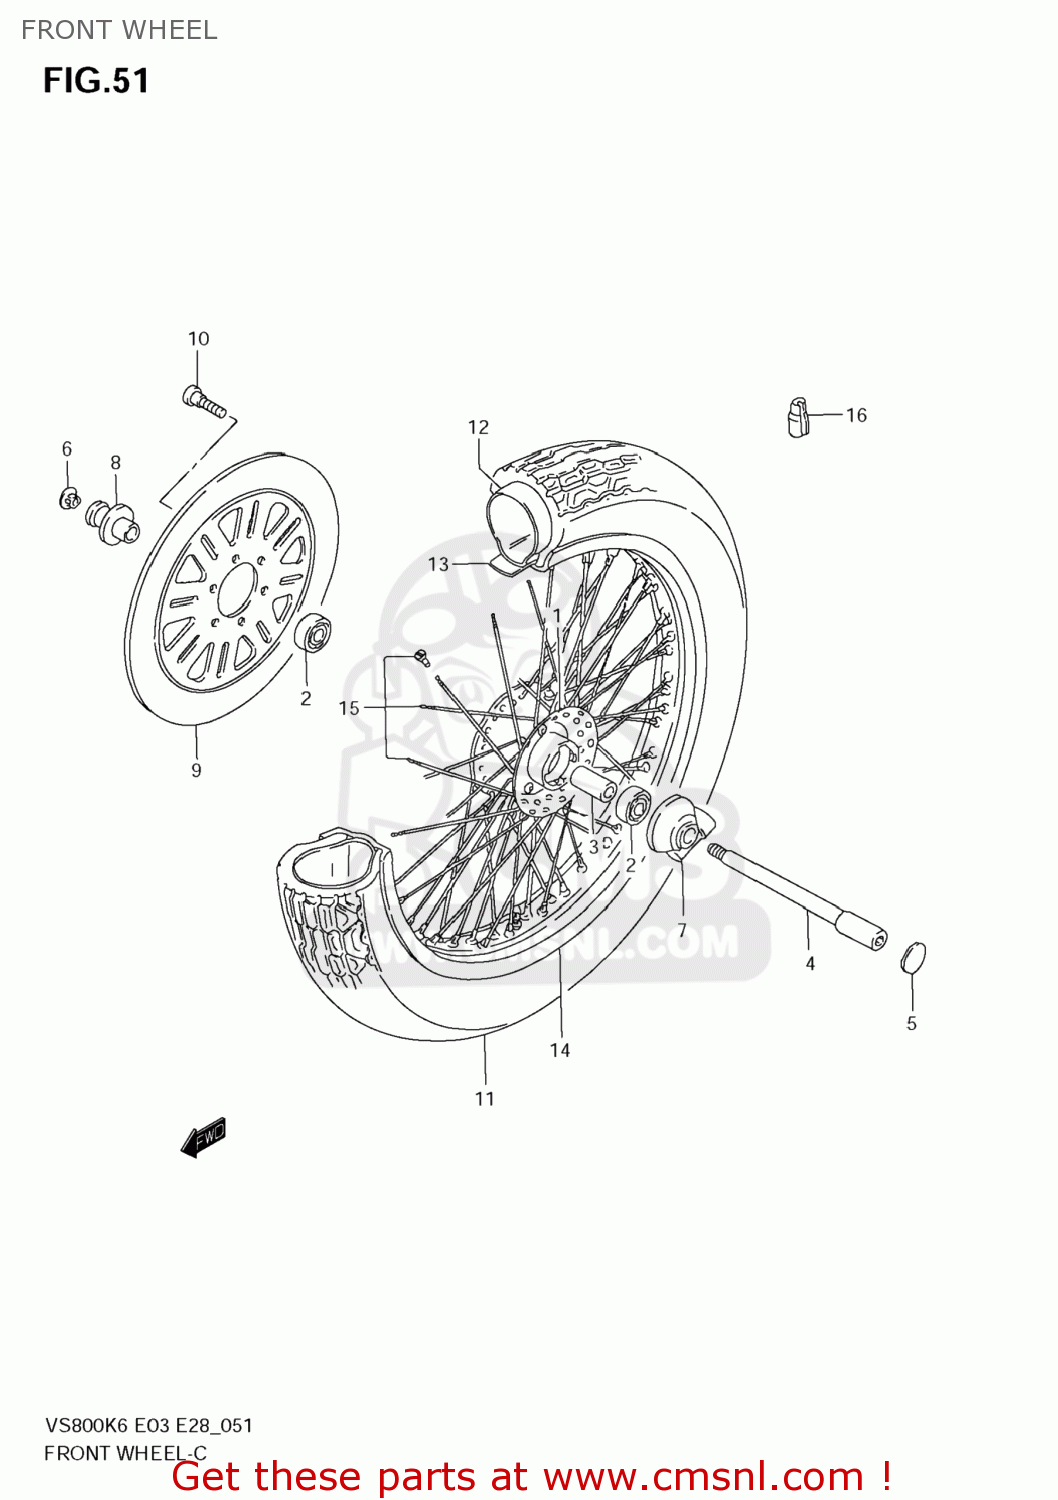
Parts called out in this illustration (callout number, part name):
1	HUB ASSY,FR
2	BEARING
3	SPACER(15.3X21.7X65)
4	AXLE,FR
5	CAP,FR AXLE
6	CAP,FR AXLE
7	BOX ASSY,SPEEDOMETER GEAR
8	SPACER,FR AXLE
9	DISC,FR BRAKE
10	BOLT(8X33)
11	TIRE,FR
12	TUBE ASSY,WHEEL INNER
13	PROTECTOR, INNER TUBE
14	RIM,FR WHEEL(19X2.15 AL)
15	SPOKE SET,FR WHEEL
16	BALANCER,WHEEL(15G)
